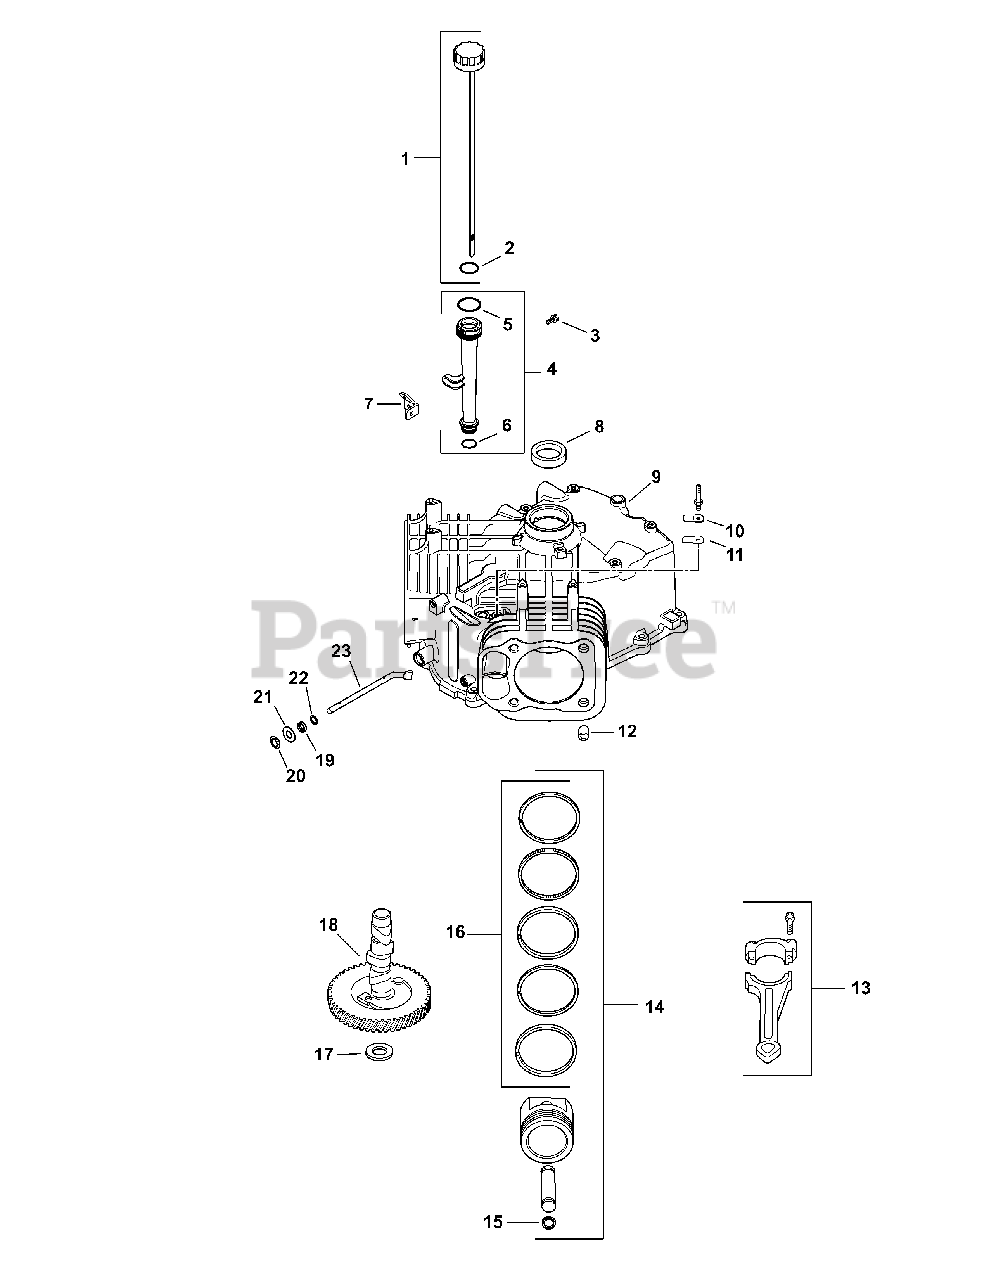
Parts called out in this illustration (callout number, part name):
1	Dipstick, Assy (Cub Yellow)
2	O-Ring, Dipstick
3	Screw, Flg Thd Frm M5x0.8x13
4	Kit, Oil Fill Cap (Includes 5, 6)
5	O-Ring, Upper Oil Fill Tube
6	O-Ring, Lower Oil Fill Tube
7	Bracket, Oil Fill Tube
9	Crankcase (use: Shortblock )
9	Shortblock
10	Retainer, Breather Reed
11	Reed, Breather
12	Pin, Locating
13	Connecting Rod (STD)
14	Kit, Piston w/ Ring (STD)
14	Kit, Piston w/ Ring (.25)
14	Kit, Piston w/ Ring (.08)
15	Retainer, Piston Pin
16	Ring Set (STD & .08)
16	Ring Set (.25)
17	Shim, Camshaft (White .028)
17	Shim, Camshaft (Blue .03)
17	Shim, Camshaft (Red .032)
17	Shim, Camshaft (Yellow .034)
17	Shim, Camshaft (Green .036)
17	Shim, Camshaft (Gray .038)
17	Shim, Camshaft (Black .04)
18	Kit, Camshaft (Includes Lubricant)
19	Seal, Governor Cross Shaft
20	Retainer Ring
21	Washer, Flat 9MM
22	Washer, Flat 11/32"
23	Shaft, Governor Cross
